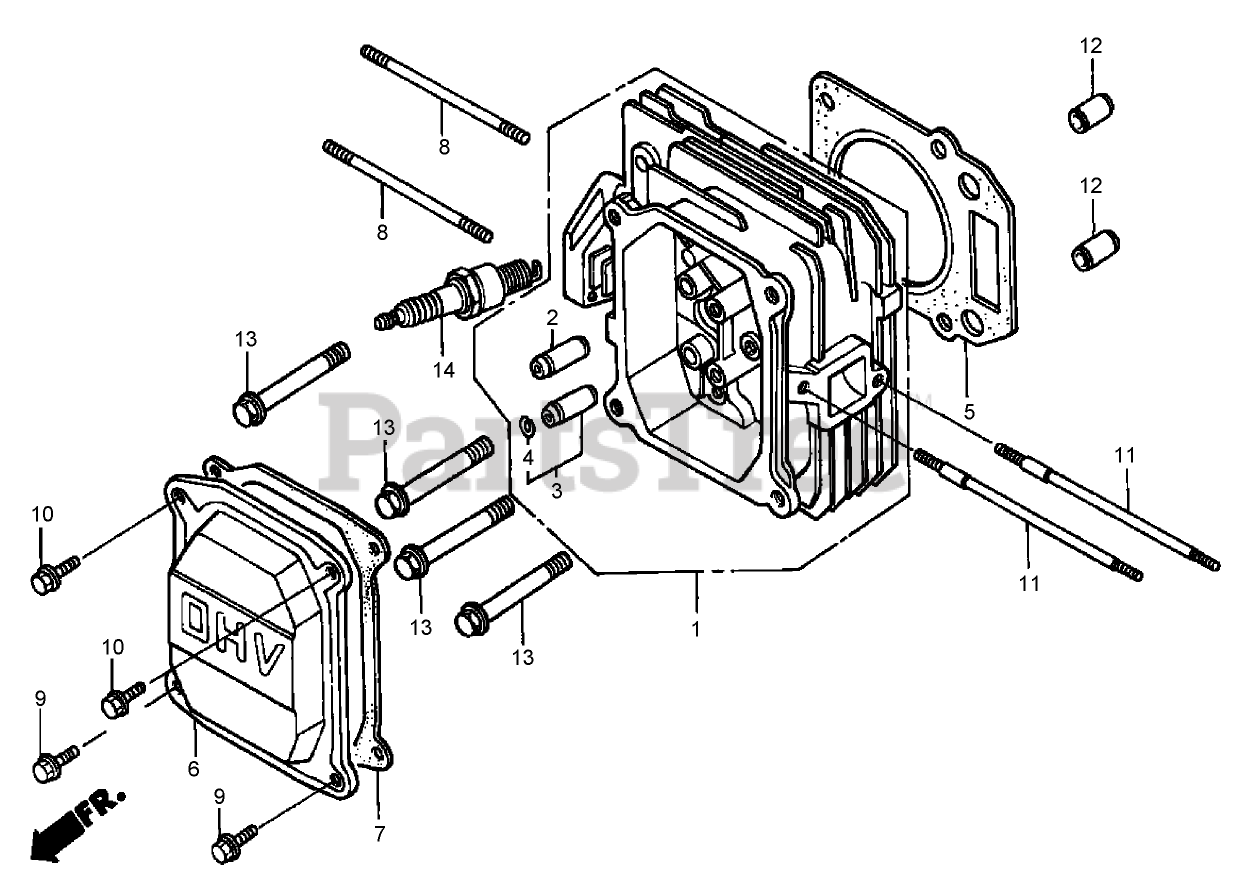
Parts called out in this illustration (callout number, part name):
1	HEAD-CYLINDER
2	GUIDE-VALVE (O S)
3	GUIDE-VALVE, EXHAUST (O S)
4	CLIP-GUIDE, VALVE
5	GASKET-HEAD, CYLINDER
6	Cover-Head
7	Gasket-COVER, Cylinder Head
8	BOLT-STUD (6X85)
9	BOLT-FLANGE (6X12) (C T200)
10	BOLT-FLANGE (6X12) (C T200)
11	BOLT-STUD (6X109)
12	PIN-DOWEL (10X16)
13	BOLT-FLANGE (8X50)
14	SPARK PLUG (B P R4E S) (N G K)
14	SPARK PLUG (W14E P R-U) (DENSO)
14	SPARK PLUG (B P R 5E S) (N G K)
14	SPARK PLUG (W16E P R-U) (DENSO)
14	SPARK PLUG (B P R 6E S) (N G K)
14	SPARK PLUG (W20E P R-U) (DENSO)
